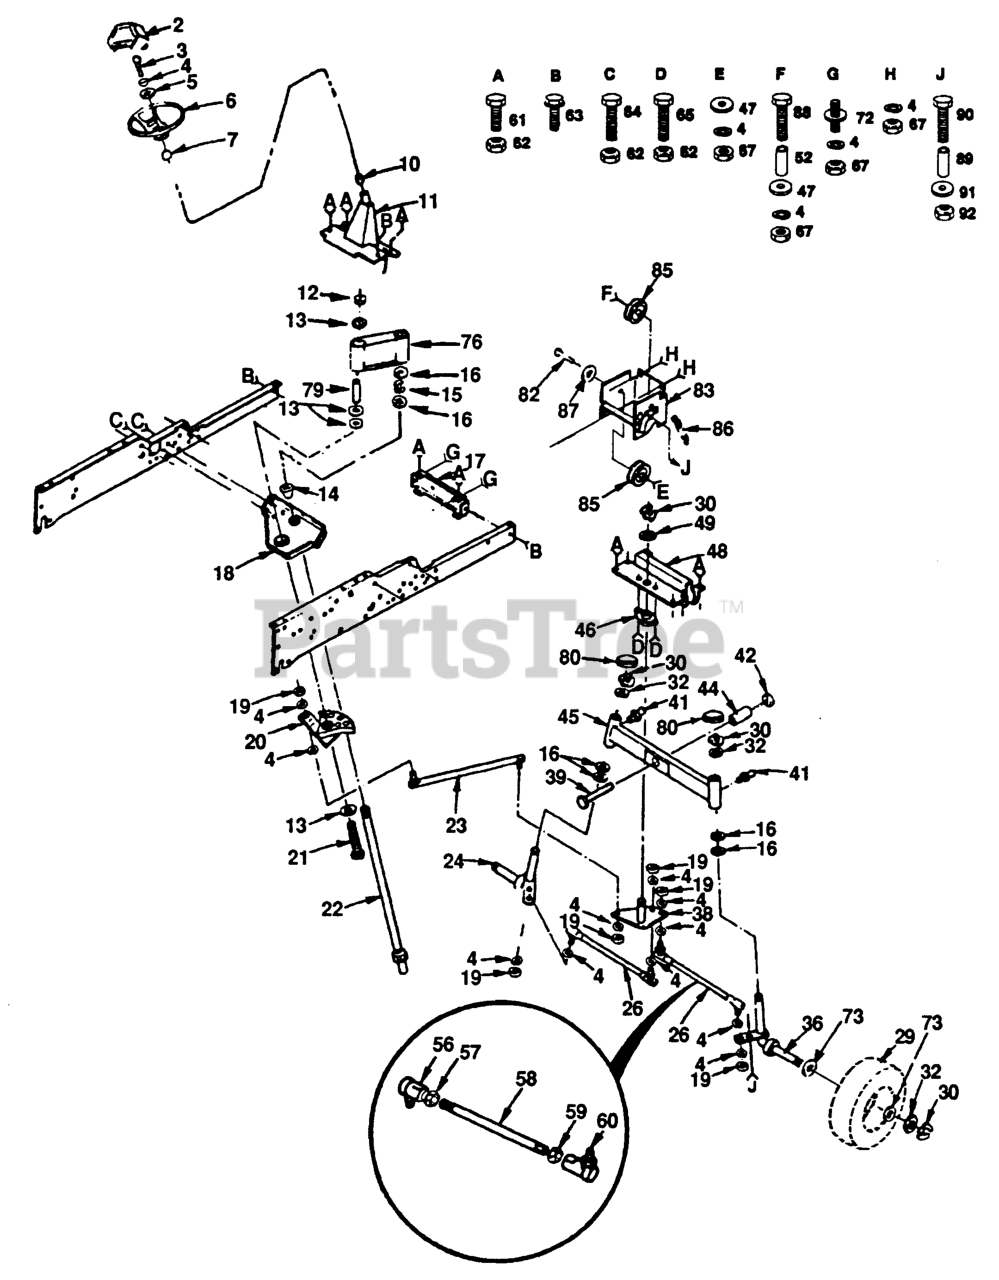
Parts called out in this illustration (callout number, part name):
2	INSERT,STR WHEEL
3	BOLT
4	WASHER, LOCK 3/8
5	WASHER T
6	STEERING WHEEL
7	ADAPTER LT
11	SUPPORT ASSY T
12	NUT LTV
13	WASHER GT
14	BEARING-FLANGE GT
16	THRUST WASHER
17	FRAME BRACKET GT
18	BRACKET ASSY GT
19	NUT
21	Bolt, Hex 1/2-13 x 5 Grade 5
22	SHAFT STEERING GT
23	DRAG LINK T
24	SPINDLE ASSY
26	ROD - NLA - NO OTHER OPTIONS
36	SPINDLE RH NLA
38	BELLCRANK T
39	Bolt, Hex 5/8-11 x 2-3/4 Grade 5
41	ZERK M
42	NUT, CROWNLOCK #10-24UNC
44	TUBE, PIVOT AXLE
45	FRONT AXLE ASSY
46	BELL CRANK BUSH T
47	Washer 13/32 x 7/8 x 13 Gauge
48	AXLE BRACKET GT
49	Washer 29/32 x 1-1/4 x 16 Gauge
52	SPLIT SPACER YTV
56	JOINT TIE ROD
58	REPL BY 532 12 11-59
63	SCREW
64	BOLT
65	BOLT
67	NUT.HEX.3/8-16UNC
72	PIN KIT T
80	CAP.SPINDLE.BLACK
82	BOLT
83	IDLER BRKT T
85	IDLER-INSIDE T
87	WASHER T
89	BUSHING LT
90	BOLT GT
91	WASHER
92	LOCKNUT
